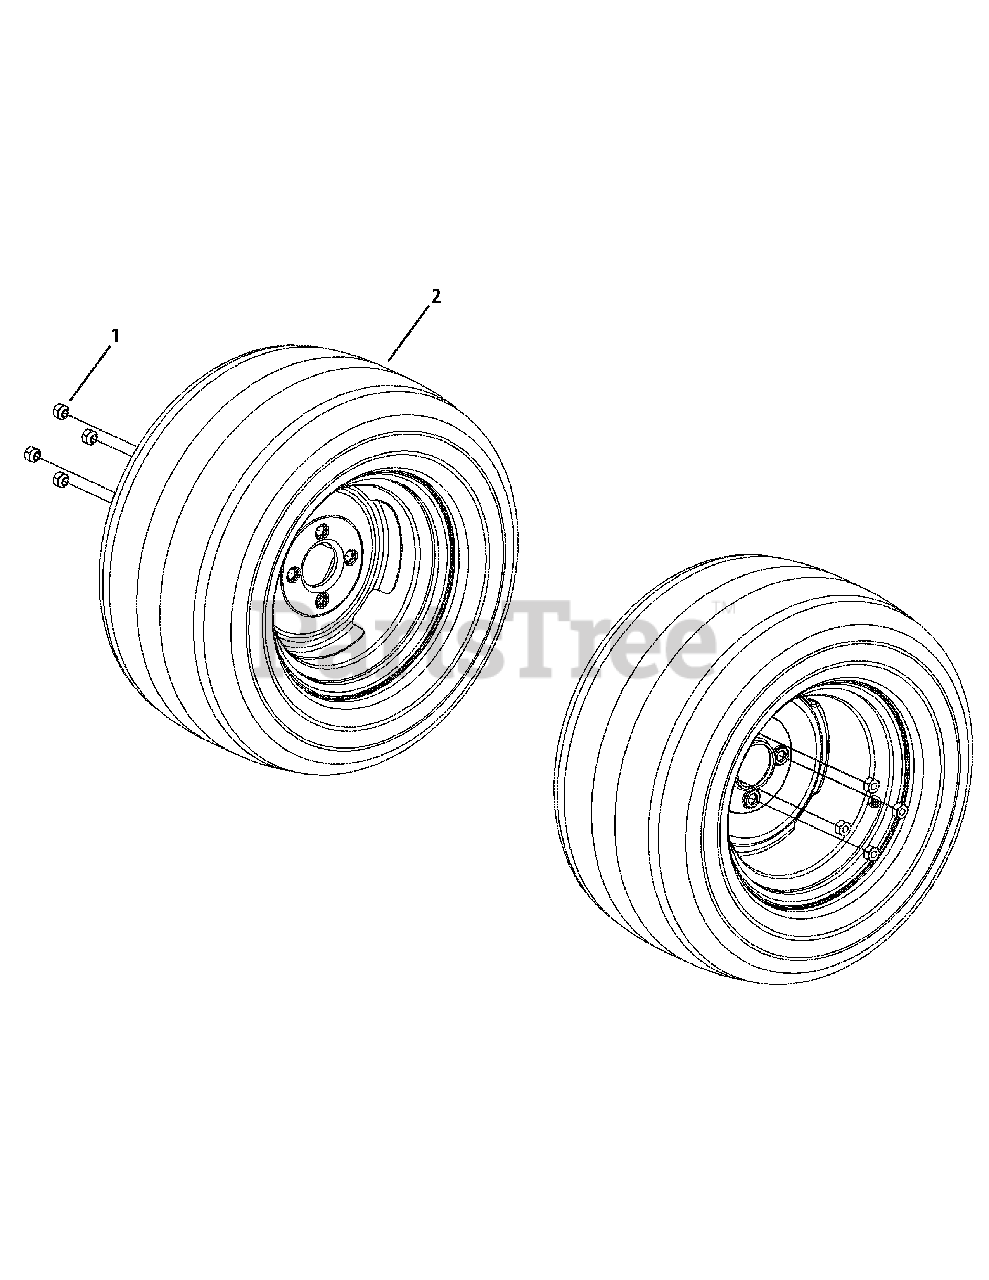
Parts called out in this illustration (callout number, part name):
1	Lug Nut, 1/2-20
2	Wheel Assembly, 9.50-12, Beige Includes:
2	Tire, 9.50-12, Turf Master
2	Rim, 12 Dia x 7.00 width
2	Wheel Assembly, 24 x12-12, Beige Includes:
2	Tire, 24 x 12-12, Turf Master
2	Rim, 12 Dia x 8.50 width
2	Wheel Assembly, 24 x 12-12, Turf Saver
2	Tire, 24 x 12-12, Turf Saver
